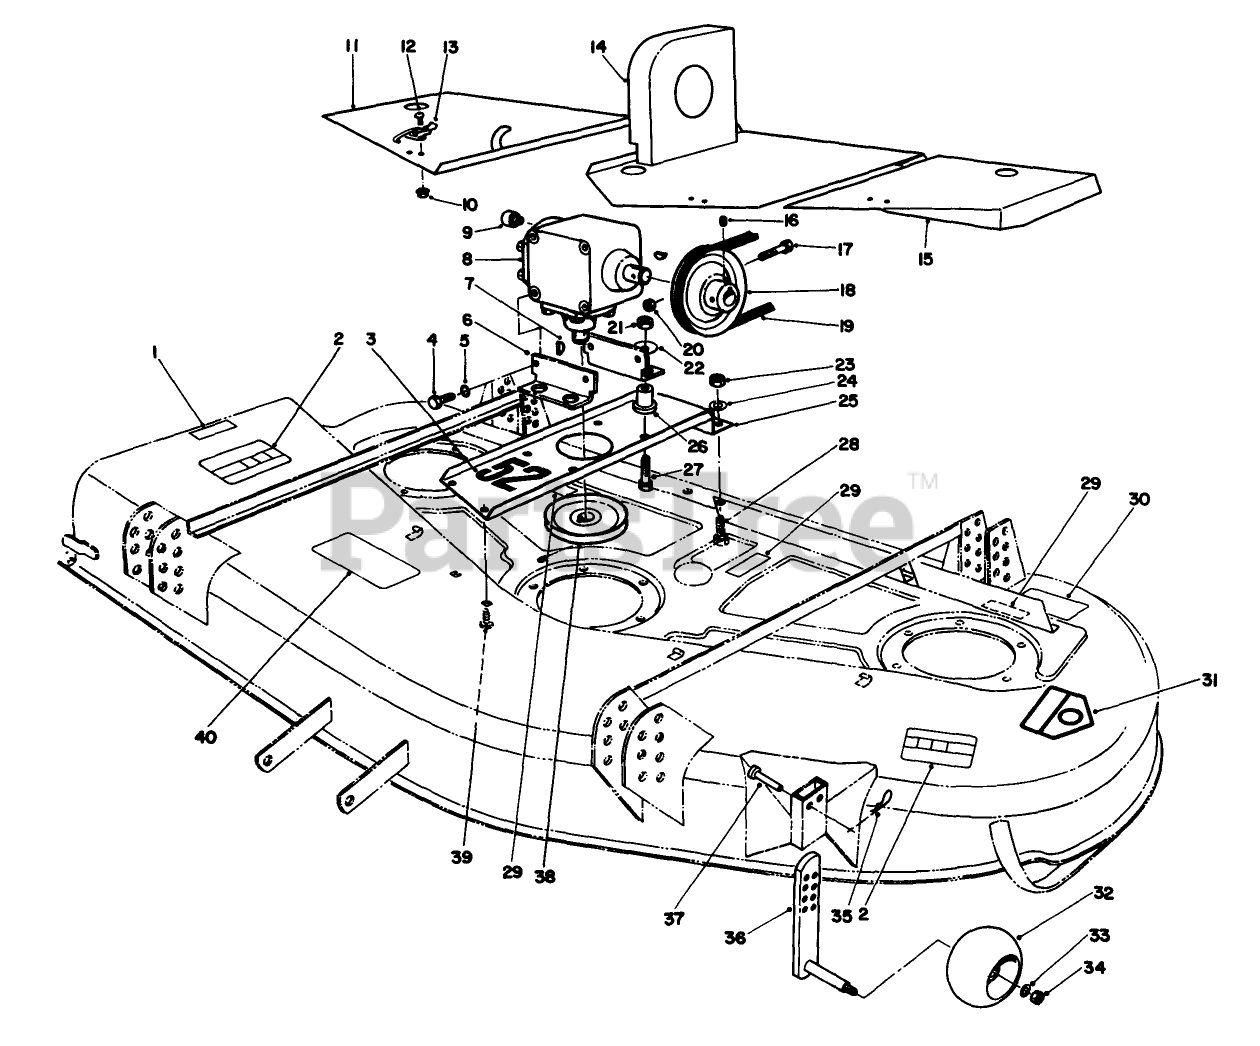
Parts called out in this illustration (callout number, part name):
1	DECAL-DANGER
2	DECAL-DANGER, THROWN OBJECT
3	DECAL
4	SCREW-HH
5	WASHER-LOCK
6	Bracket Mounting
8	Gear Box
9	FITTING-LUBE
10	NUT-LOCK, FLANGE
11	Bolt
12	SCREW-HWH
13	CLAMP-SLOTTED
14	Center-Cover
15	Cover-Deck
16	SCREW-SET, SQH
17	SCREW-HH
18	PULLEY
19	V-BELT, DECK
20	NUT-LOCK, NI
21	NUT-LOCK, SIDE
22	WASHER
23	NUT-LOCK, NI
24	WASHER-FLAT
25	Base-Gear Box Mount
26	MOUNT
27	SCREW-HH
28	SCREW-HH
29	DECAL-DANGER
30	DECAL-TORQUE
31	DECAL-DANGER
32	WHEEL-GAGE
33	WASHER-FLAT
34	NUT-LOCK, NI
35	PIN-HAIR
36	GAGE-WHEEL
37	PIN-CLEVIS
38	PULLEY
39	BOLT-CARR
40	DECAL-WARNING
